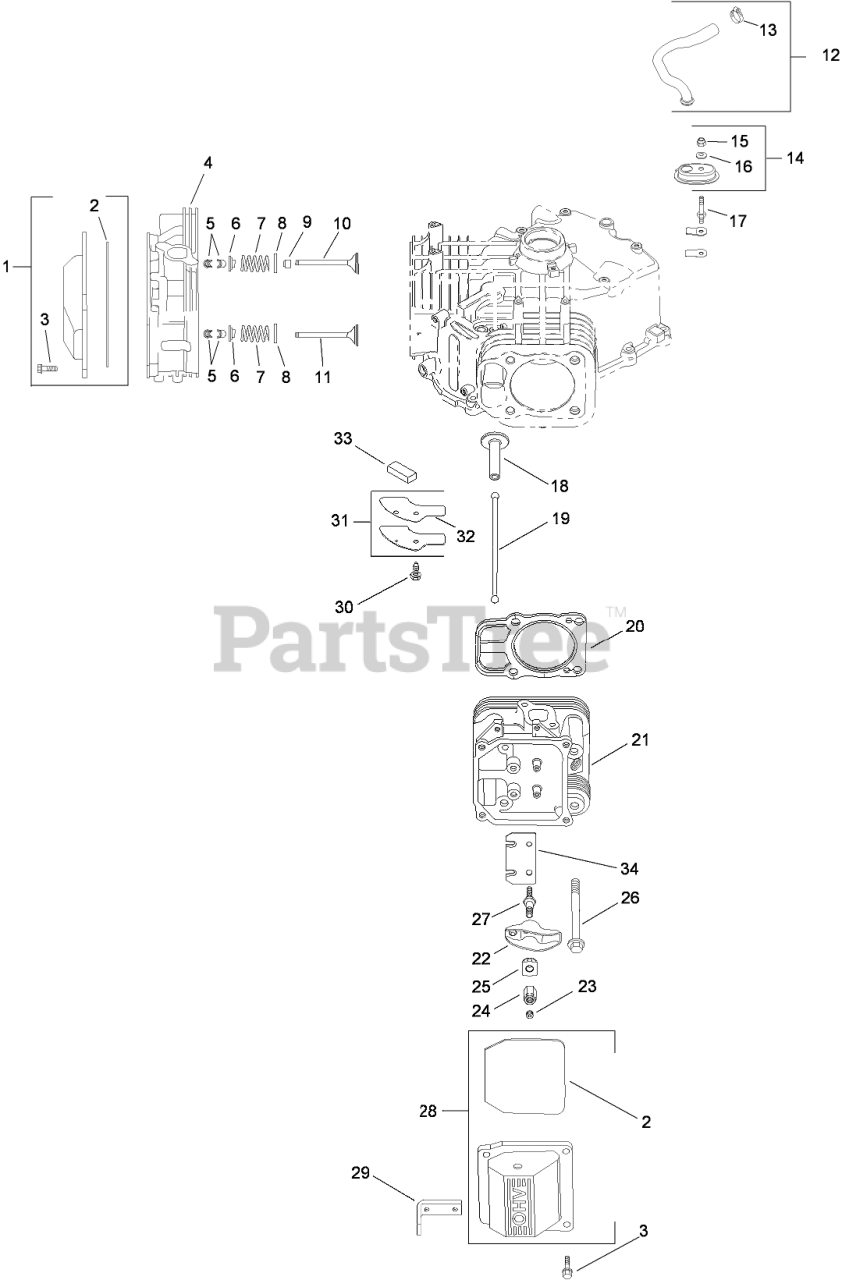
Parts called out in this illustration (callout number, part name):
1	PLAIN ROCKER COVER KIT
2	O-RING
3	SCREW-FLANGE (M6X1.0X30)
4	No.1 CYLINDER HEAD KIT ASM
5	RETAINER KIT
6	CAP-SPRING, VALVE
7	SPRING-VALVE
8	RETAINER-SPRING
9	SEAL-STEM, VALVE
10	VALVE-INTAKE (STD)
11	VALVE-EXHAUST (STD)
12	BREATHER HOSE KIT
13	CLAMP-HOSE, SPRING (1/2)
14	BREATHER HOUSING KIT (INCLUDES 15-16)
15	NUT-LOCK (M5X.8)
16	WASHER-SEALING
17	STUD-COVER, BREATHER
18	TAPPET KIT
19	ROD-PUSH
20	CYLINDER HEAD GASKET KIT
21	CYLINDER No.2 HEAD ASM
22	ARM-ROCKER
23	NUT (M10X0.75 )
24	SCREW-SET
25	PIVOT-ARM, ROCKER
26	SCREW-FLANGE (M10X1.5X90)
27	STUD-ROCKER
28	BREATHER VALVE COVER KIT
29	STRAP-LIFTING
30	SCREW-FLANGE, THREAD FORMING (M6X1.0X16)
31	BREATHER COVER KIT
32	GASKET-COVER, BREATHER
33	FILTER-BREATHER
34	PLATE-GUIDE
36	O-RING
